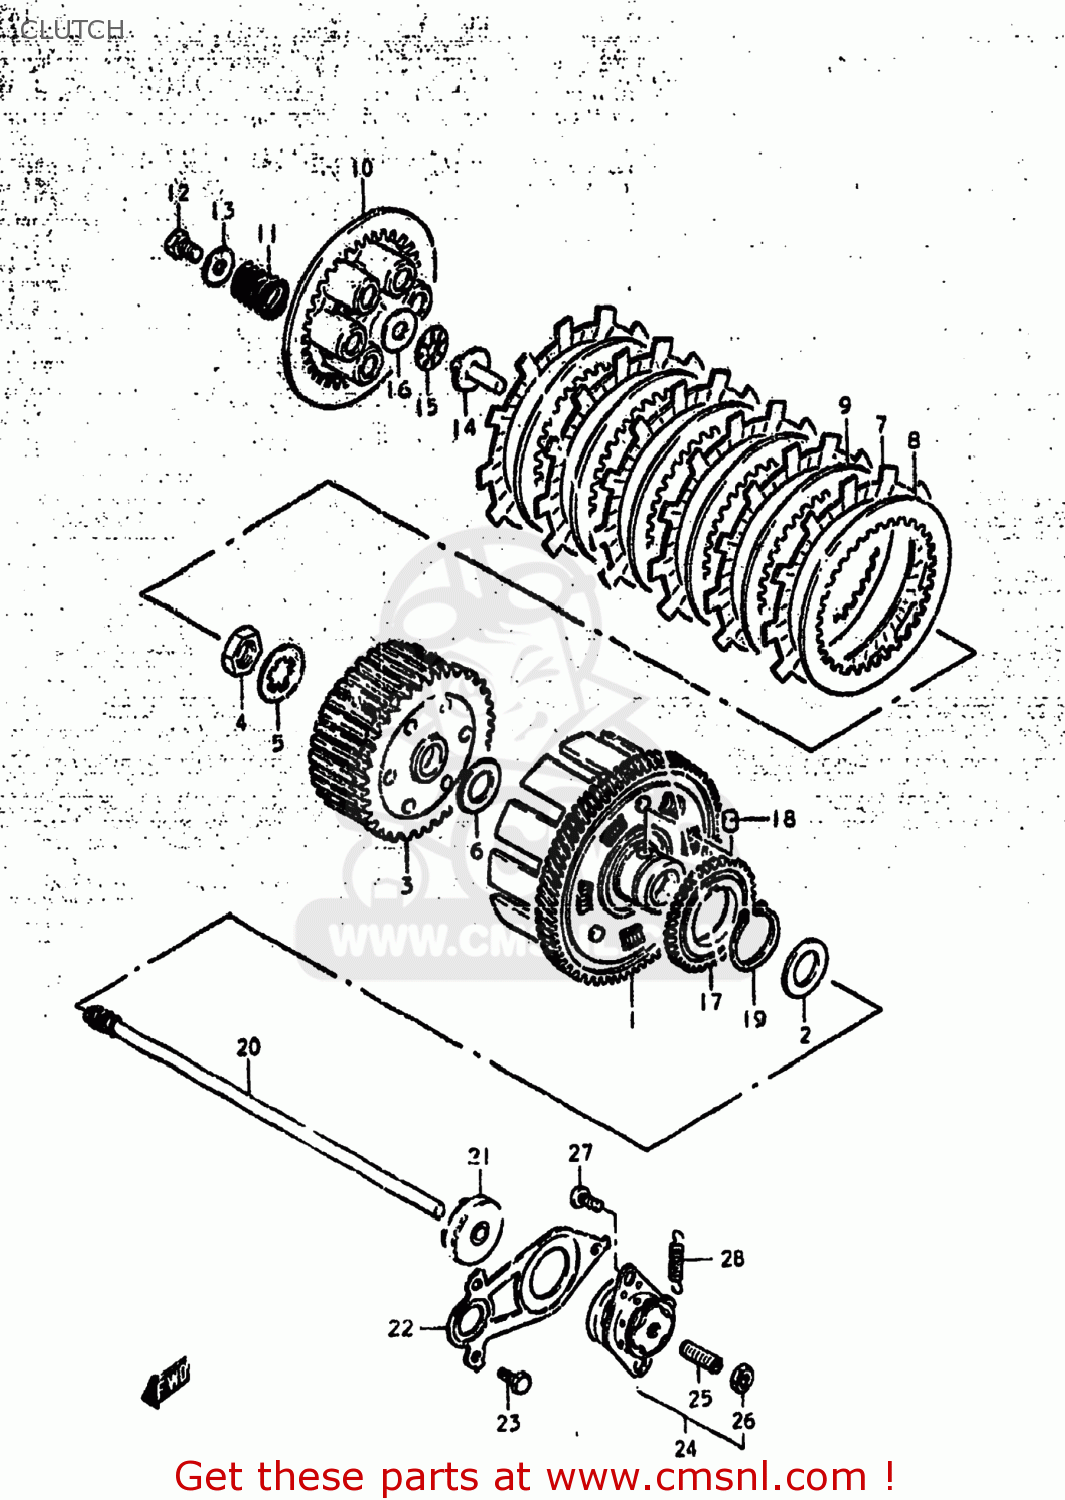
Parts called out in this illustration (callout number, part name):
1	GEAR ASSEMBLY,PRIMARY DRIVE
2	WASHER
3	HUB,CLUTCH SLEEVE
4	NUT (20MM)
5	WASHER,LOCK
6	WASHER(20X38X2)
7	PLATE,CLUTCH DRIVE (NAS)
8	PLATE,CLUTCH DRIVEN(T:2.0) (NAS)
9	PLATE,CLUTCH DRIVEN (NAS)
10	DISC,CLUTCH PRESSURE
11	SPRING
12	BOLT, UPPER
13	WASHER
14	PIECE,CLUTCH PUSH
15	BEARING(15X28X2)
16	WASHER
17	GEAR,OIL PUMP DRIVE
18	PIN(6X6)
19	CIRCLIP
20	ROD,CLUTCH PUSH
21	OIL SEAL
22	RETAINER,CL PUSH ROD OIL SEAL
23	BOLT
24	SCREW ASSEMBLY,CLUTCH RELEASE
25	SCREW
26	NUT 6MM
27	SCREW 6X12
28	SPRING
